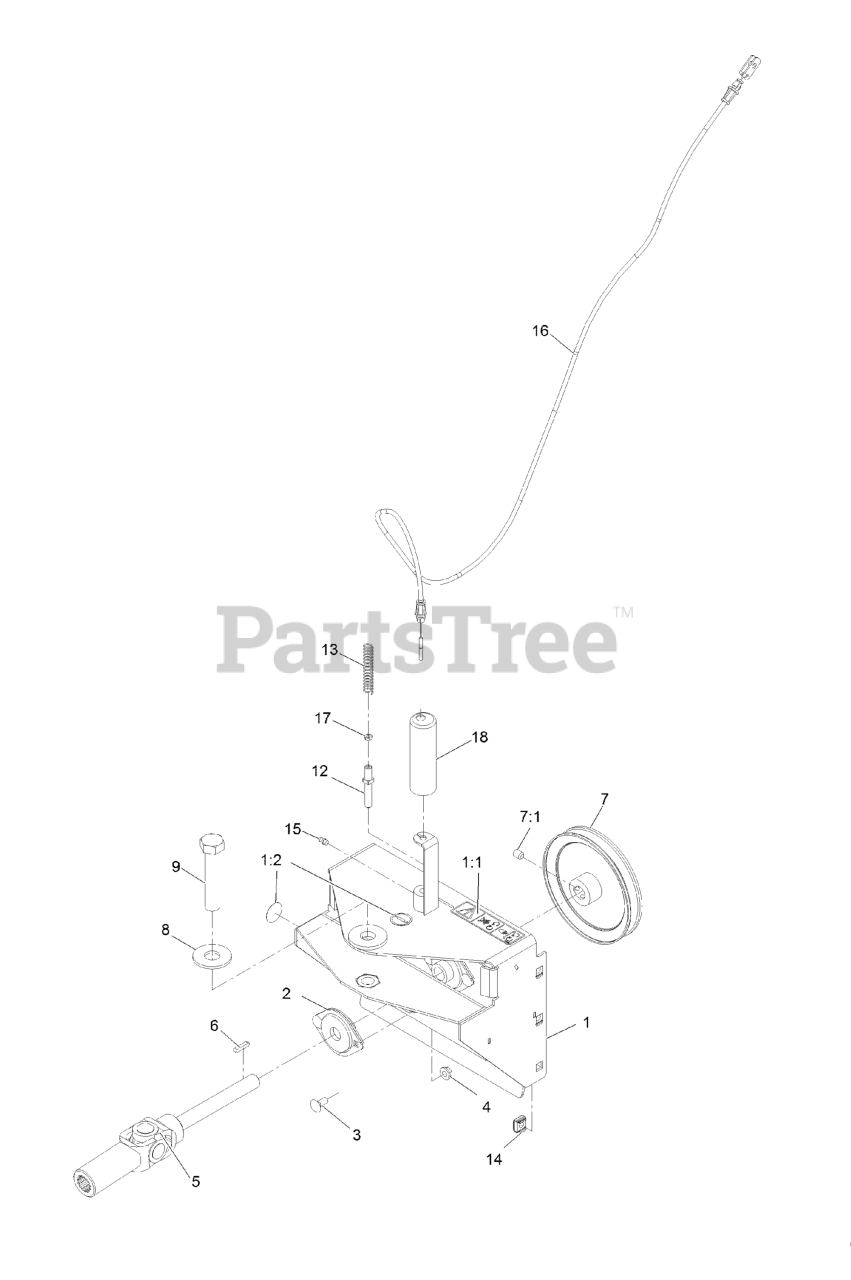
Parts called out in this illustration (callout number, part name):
1	BROOM MOUNTING FRAME ASM
1:1	DECAL-COVER, MISSING
1:2	DECAL-GREASE
2	BEARING-SHAFT
3	BOLT-CARR
5	SHAFT-DRIVE
6	KEY-ROUND END
7	PULLEY-IMPELLER
7:1	SETSCREW
8	WASHER-FLAT
9	SCREW-HH
12	PIN-SWING
13	SPRING-COMPRESSION
14	NUT-RETAINER
15	FITTING-GREASE
16	CABLE-ANGLE, BROOM
17	NUT-HEX
